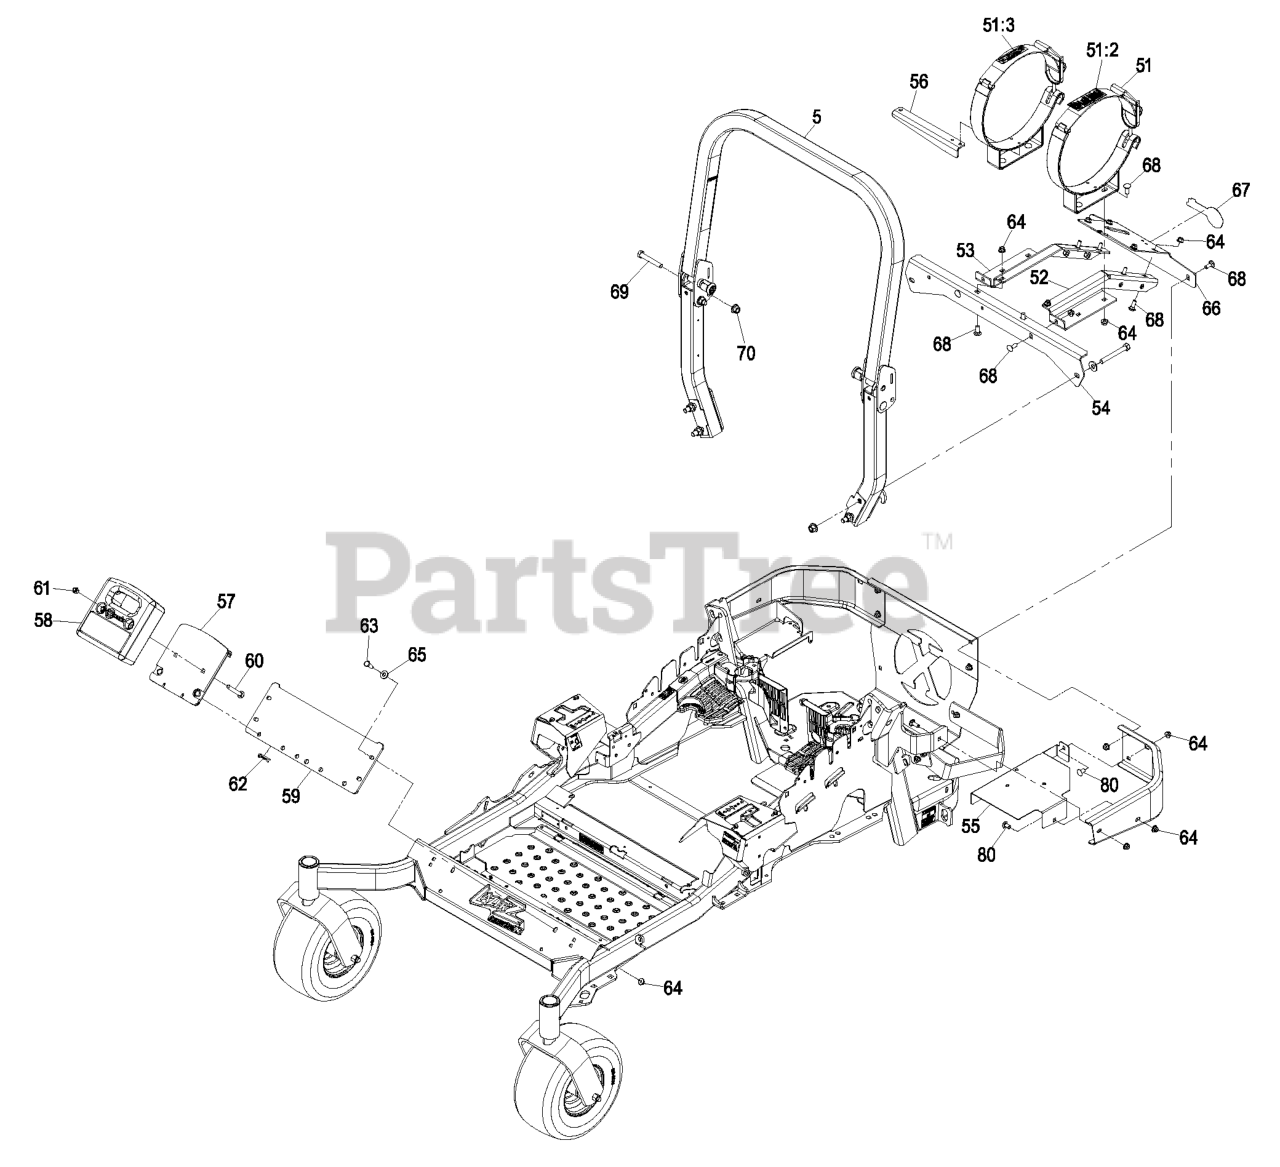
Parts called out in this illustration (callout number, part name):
5	ROPS ASM
51	TANK BRACKET ASM (SET)
51:2	DECAL-LPG WARNING
51:3	DECAL-LPG 43.5LB TANK
52	LH LPG FRAME ASM
53	RH LPG FRAME ASM
54	SUPPORT-LPG FRAME, FRONT
55	BRACKET-AIR, LPG CLEANER
56	PLATE-INDEX, LPG TANK
57	WLD,WEIGHT MOUNT
58	WEIGHT,CAST 36LB
59	PLATE,WEIGHT ASM MOUNT
60	SCREW-CARR
61	NUT-LOCK, NI
62	PIN-HAIR
63	SCREW-HH
64	NUT-HF, NI
65	WASHER-BELLEVILLE
66	SUPPORT-REAR FRAME, LPG
68	BOLT-CARR
69	SCREW-HH
70	Nut-Lock 1/2-13
80	SCREW-CARR
